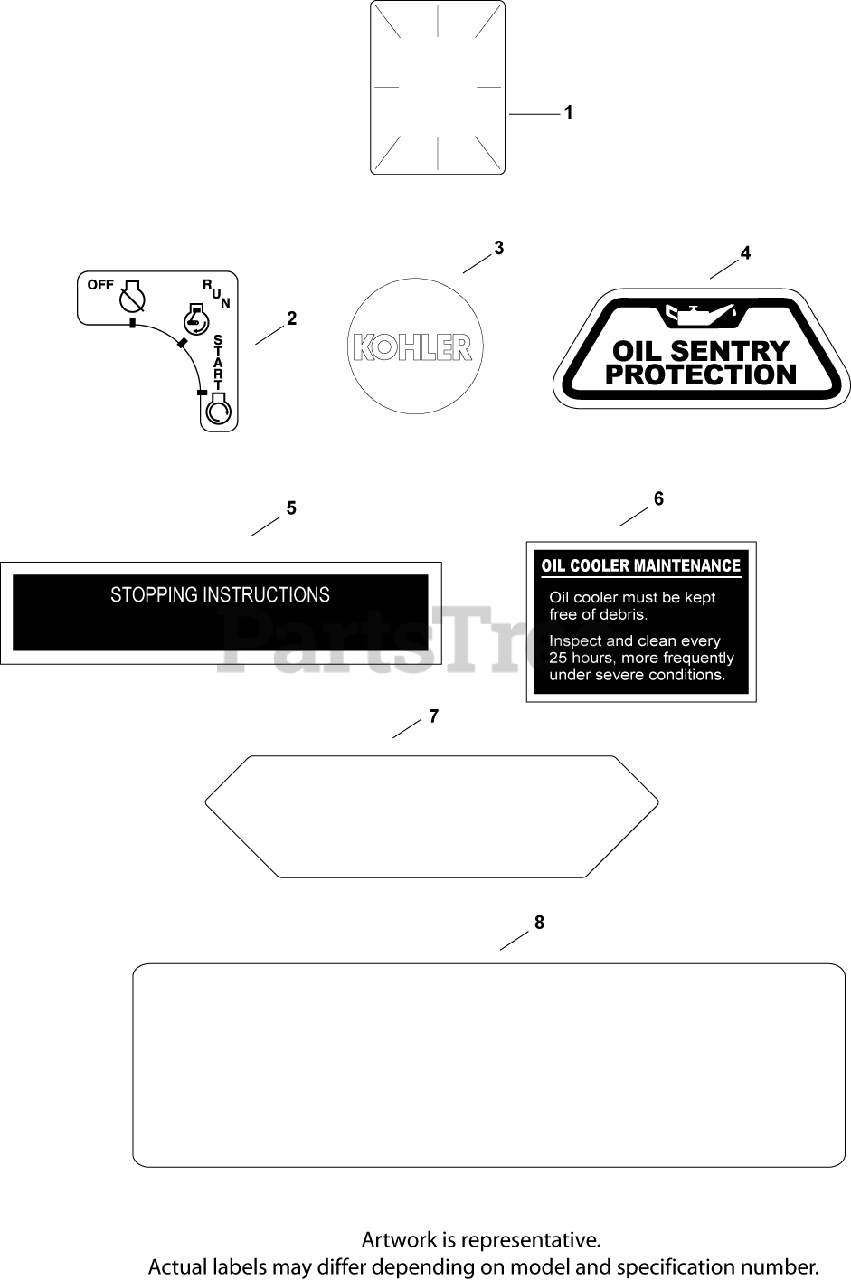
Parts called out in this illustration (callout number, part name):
1	DECAL, CLEAR LAMINATE USE 25 113 70-S
2	DECAL, STOPPING INSTRUCTION
3	LABEL, (ROUND KOHLER GOLD)-USE 24 113 18
4	DECAL, OIL SENTRY - (#DSC)
5	DECAL, STOPPING INSTRUCTION
6	DECAL, OIL COOLER - (#DSC)
7	DECAL, AIR FILTER COVER - DISC.
8	DECAL, 27 HP
